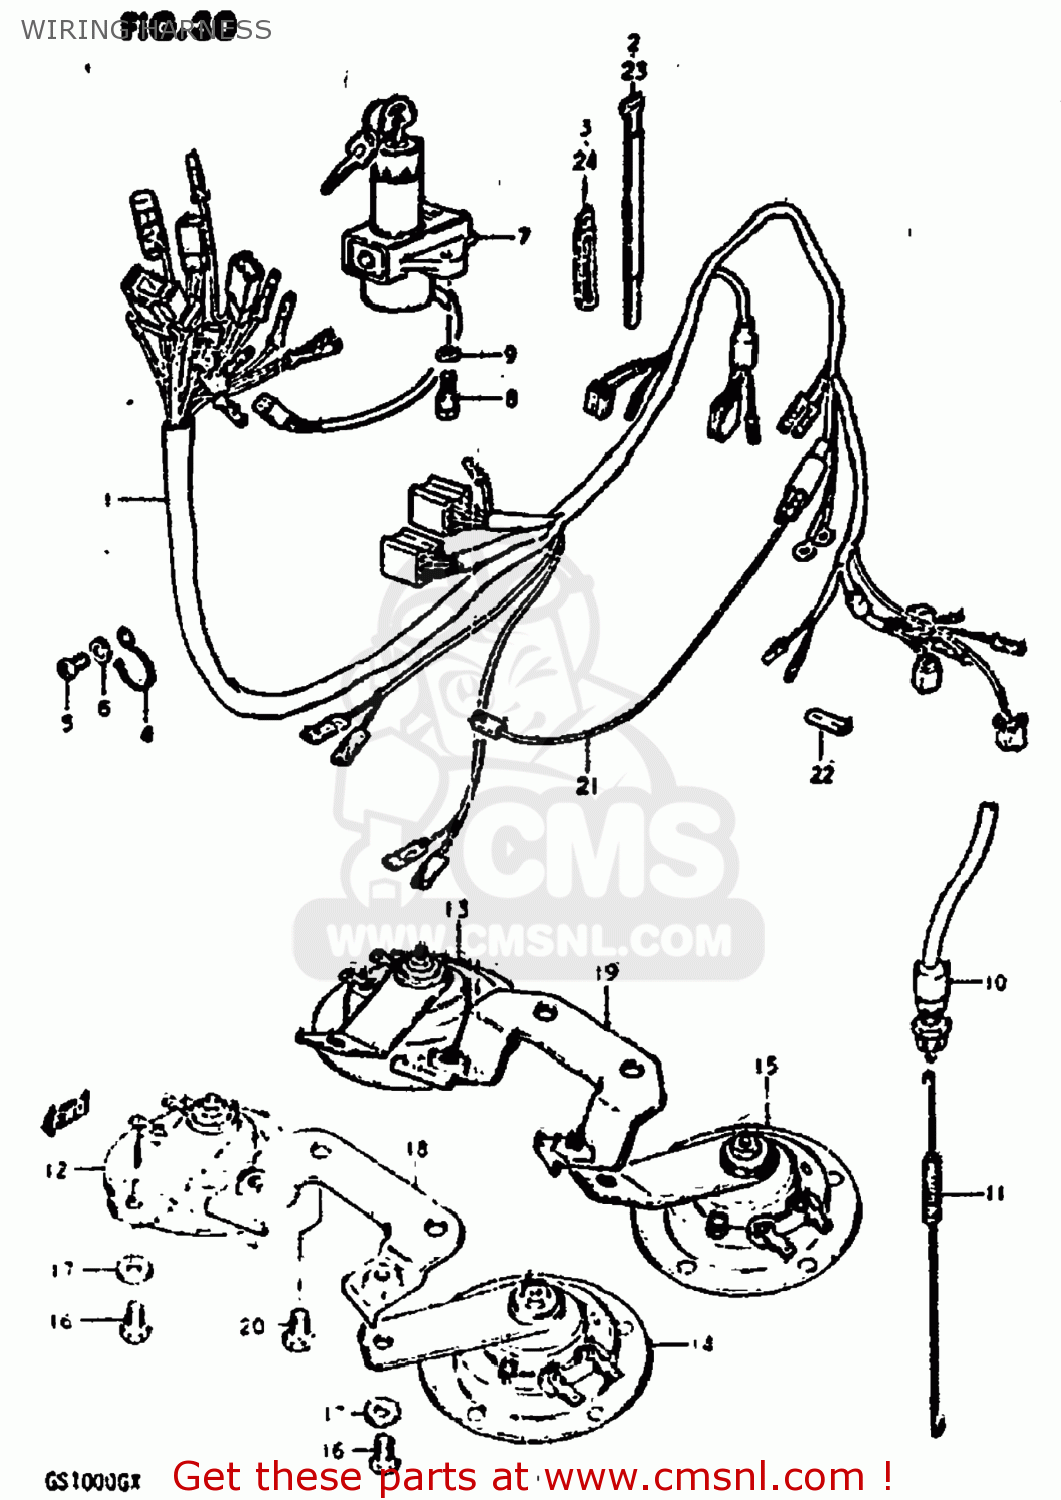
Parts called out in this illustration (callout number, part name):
1	HARNESS,WIRING
2	CLAMP
3	CLAMP
4	GUIDE,WIRING HARNESS
5	SCREW 6X12
6	WASHER
7	LOCK ASSEMBLY,STEERING
8	BOLT
9	LOCK WASHER
10	SWITCH ASSEMBLY,STOP LAMP
11	SPRING
12	HORN ASSEMBLY,LOW PITCH
13	HORN ASSEMBLY,LOW PITCH
14	HORN ASSEMBLY,HIGH PITCH
15	HORN ASSEMBLY,HIGH PITCH
16	BOLT
17	SMALL FLAT WASHER
18	BRACKET,HORN
19	BRACKET,HORN
20	BOLT 8X12
21	WIRE
22	PROTECTOR,WIRING HARNESS
23	CLAMP(L:120)
24	CLAMP
